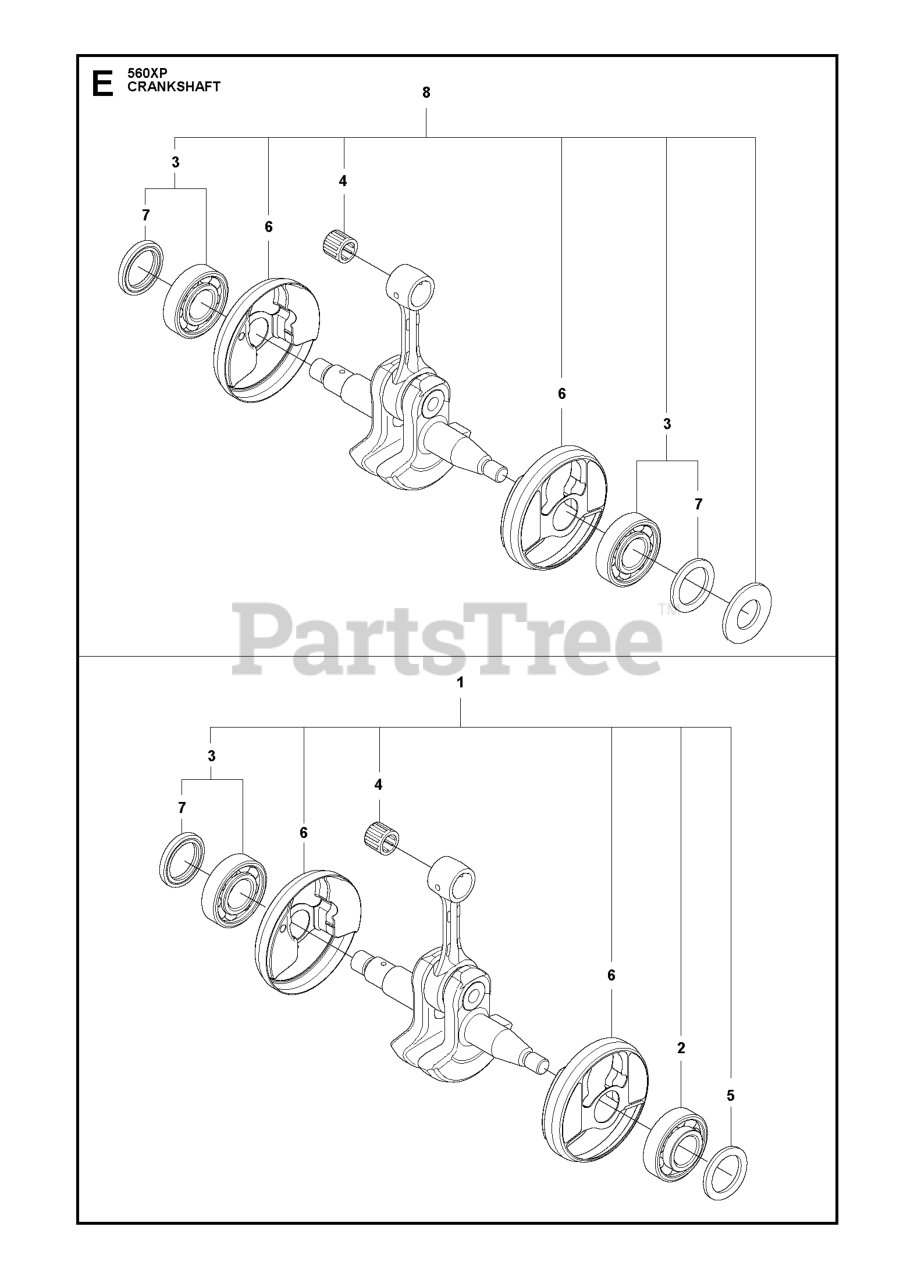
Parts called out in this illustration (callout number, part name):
1	CRANKSHAFT ASSY
2	BEARINGS
4	SUPPORT BUSHING
5	RADIAL SEAL
7	RADIAL SEAL
8	CRANKSHAFTS
